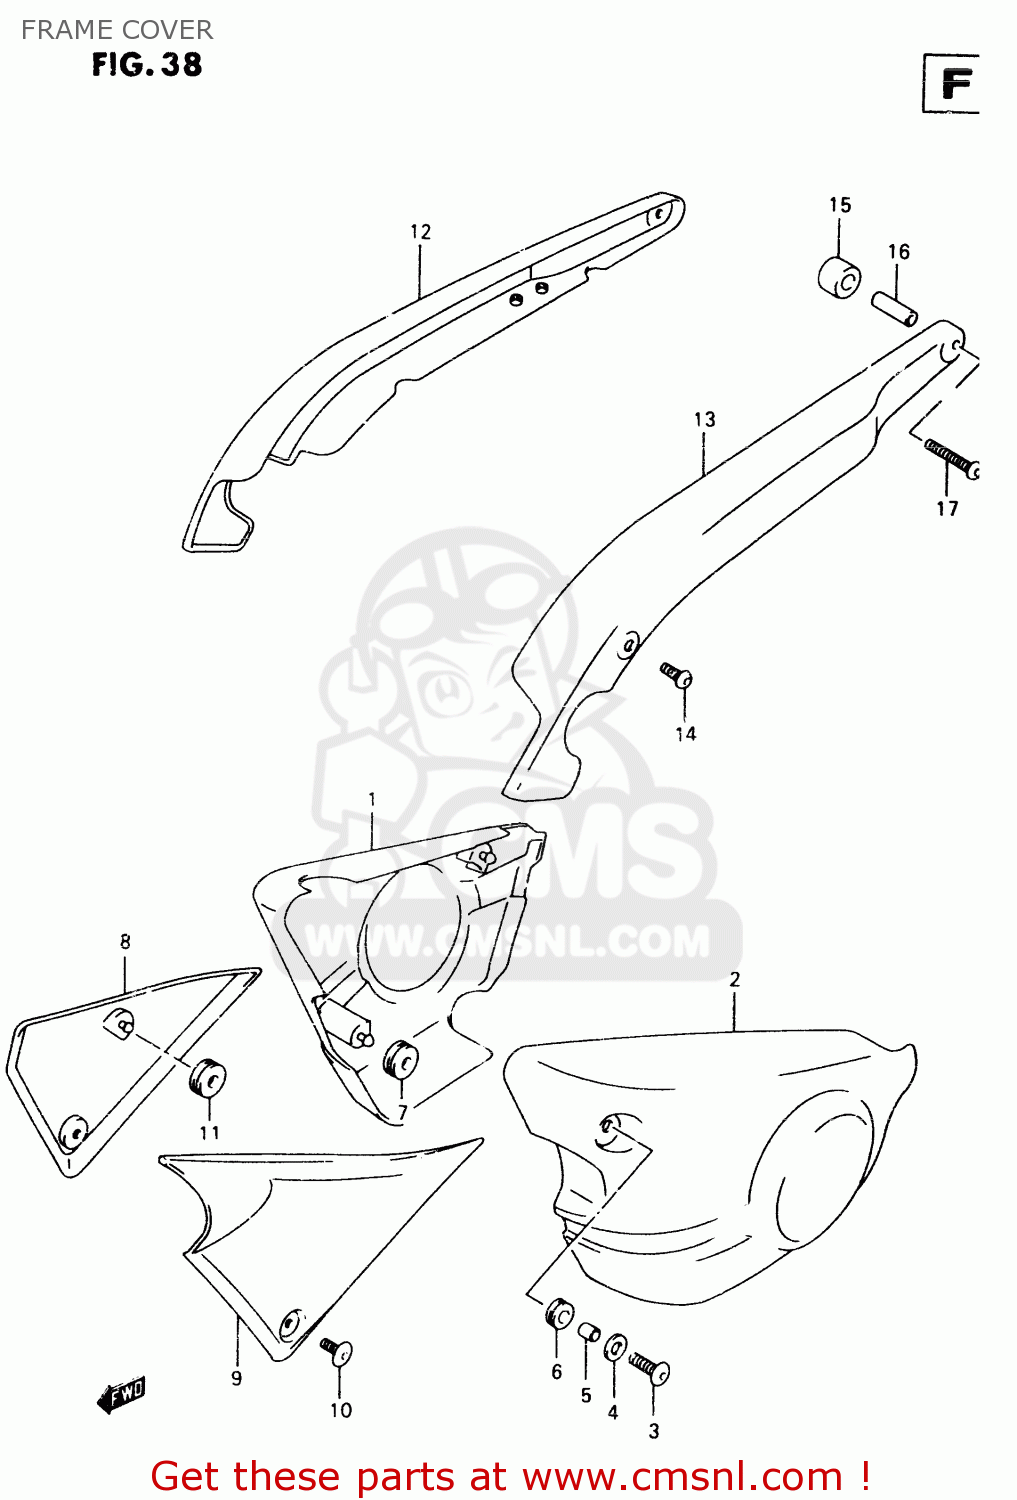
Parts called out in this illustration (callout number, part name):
1	COVER,FRAME,R
2	COVER,FRAME,L
3	SCREW(6X16)
4	WASHER(6.5X18X1)
5	SPACER(6.5X9X9)
6	CUSHION
7	CUSHION
8	COVER,FRAME HEAD,R
9	COVER,FRAME HEAD,L
10	SCREW(6X16)
11	CUSHION
12	COVER,FRAME RR,R
13	COVER,FRAME RR,L
14	BOLT(8X16)
15	CUSHION,FRAME RR COVER RR
16	SPACER(8.5X12X23.5)
17	BOLT
